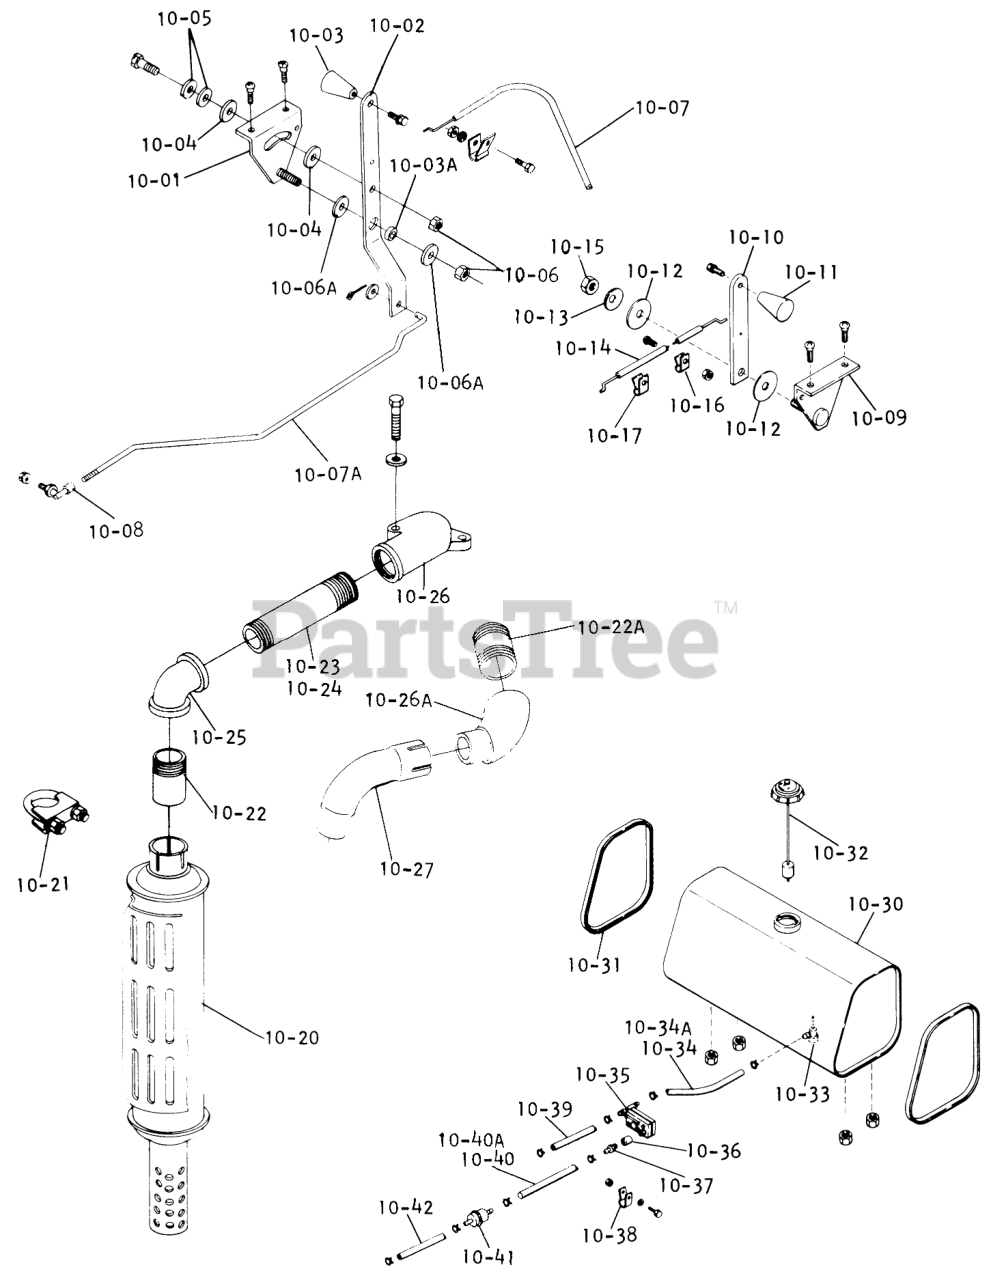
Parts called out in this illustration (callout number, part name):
10-01	Assy-Bracket
10-02	Handle Throttle
10-03A	SPACER CLUTCH ARM
10-04	FRICTION WASHER
10-05	WASHER-SPRING DISC
10-06	3/8-16 E.S.
10-06A	Washer-3/8
10-07	Throttle Rod, D-160
10-07A	Rod-Throttle
10-08	BALL JOINT ASSY R
10-09	Assy-Bracket
10-10	HANDLE
10-12	FRICTION WASHER
10-13	WASHER-SPRING DISC
10-14	Choke Control, D-160
10-16	CLIP BOWDEN WIRE
10-17	THROTTLE CONTROL CLP
10-20	ASSEMBLY MUFFLER
10-21	ASSY-MUFFLER CLAMP
10-22	Nipple
10-22A	Nipple-Exhaust, 1 1/4 x 1-5/8, D-160
10-23	Nipple 1" Pipe x 2"
10-24	Nipple-Exhaust 1 X 5
10-25	Elbow 90 X 1
10-26	Fitting Exhaust RH
10-26A	Exhaust Fitting, D-160
10-27	TUBE-INLET
10-30	Fuel Tank
10-31	Edge Trim
10-32	GAUGE CAP
10-33	FILTER & VALVE ASSY
10-34	Fuel Line 62
10-34A	Fuel Hose
10-35	Pump Fuel
10-36	Coupling 1/8" Pipe
10-37	Straight Fitting
10-38	CLAMP-HOSE
10-39	Fuel Hose
10-40	Hose
10-40A	Hose-Fuel
10-41	Filter
10-42	Fuel Hose
